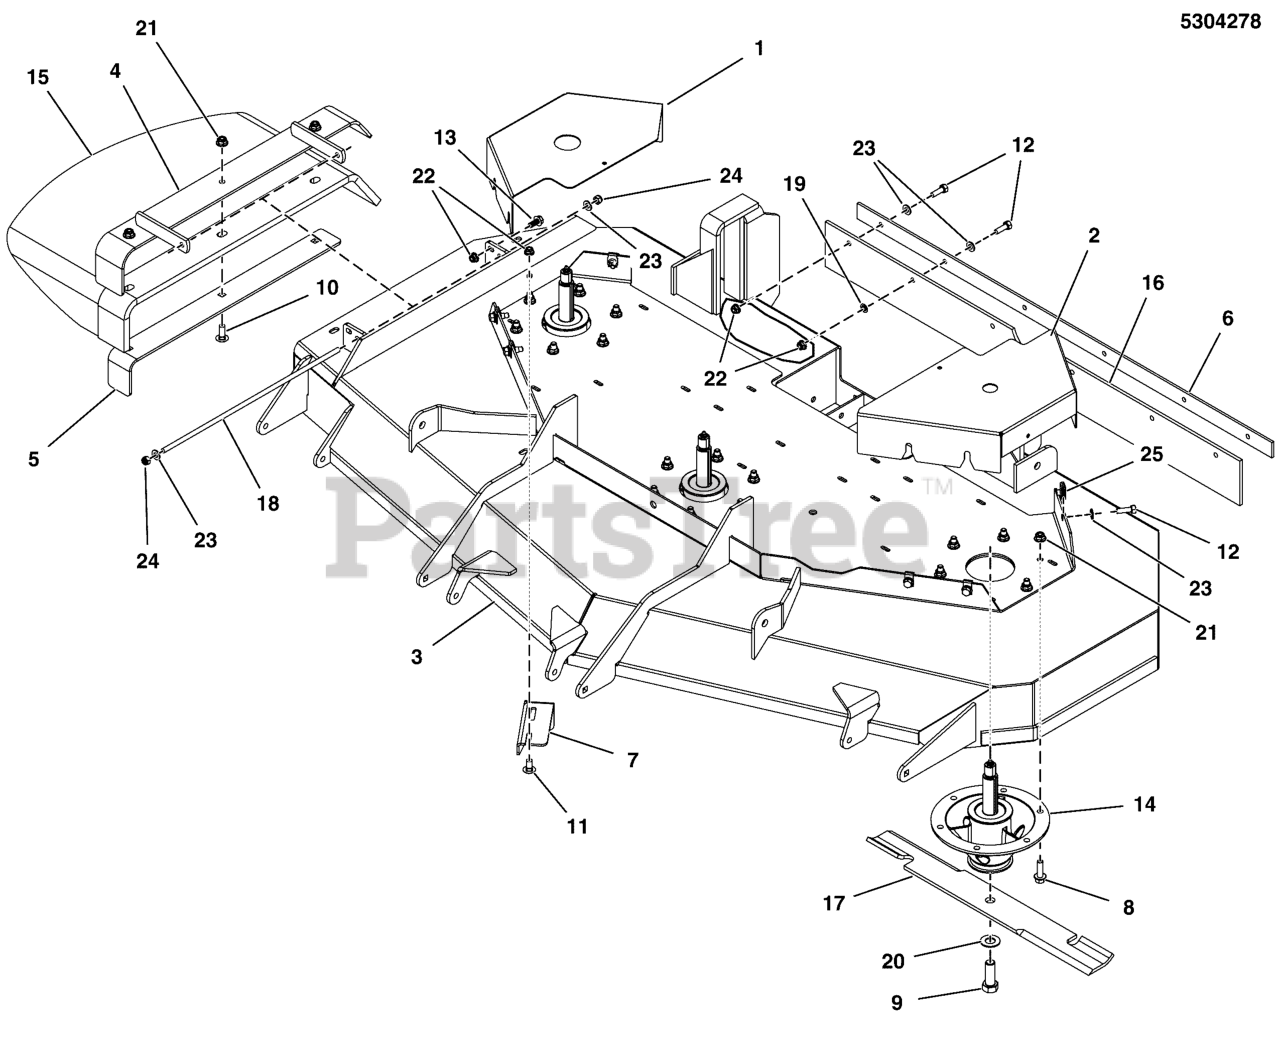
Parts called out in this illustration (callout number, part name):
1	GUARD, RH 61 DECK, SRSZ2 - RED
2	GUARD, LH 61 DECK, SRSZ2 - RED
3	DECK SHELL W/DECALS 61 SRSZ2 5414261B
5	SUPPORT, DISCHARGE CHUTE - BLK
6	PLATE, SUPPORT - BLK
7	PLATE, DEFLECTOR - BLK
8	BOLT, 3/8-16 X 1-1/4, FLANGE, GD 5, CZ
9	BOLT, 5/8-11 X 1-3/4 GD8
10	BOLT, 3/8-16 X 1-1/2, CARRIAGE, GD5, CZ
11	BOLT, 5/16-18 X 3/4, CARRIAGE, GD5, CZ
12	BOLT, 5/16-18 X 1" GRD5 YZ
13	BOLT, 5/16-18 X 3/4 GD5
14	SPINDLE ASSM, CAST IRON 8.0-6 BOLT, LS
15	CHUTE, RUBBER DISCHARGE (5104442)
16	FLAP, STRIPER, 61 DECK
17	BLADE SET, 61 DECK (3)
18	ROD, MOUNT, CHUTE, 61, CZ
19	5/16" PUSH-ON NUT RETAINER, STL, CZ
20	WASHER, BLADE BOLT, 9/16" F436, CZ
21	NUT, 3/8 - 16 HEX NYLOCK FLANGE
22	NUT, 5/16-18 HEX NYLOCK FLANGE NUT
23	WASHER, 5/16" SAE
24	NUT, 5/16-24 HEX NYLON LOCK
25	BODY CLIP, 5/16-18-7GA MATERIAL
